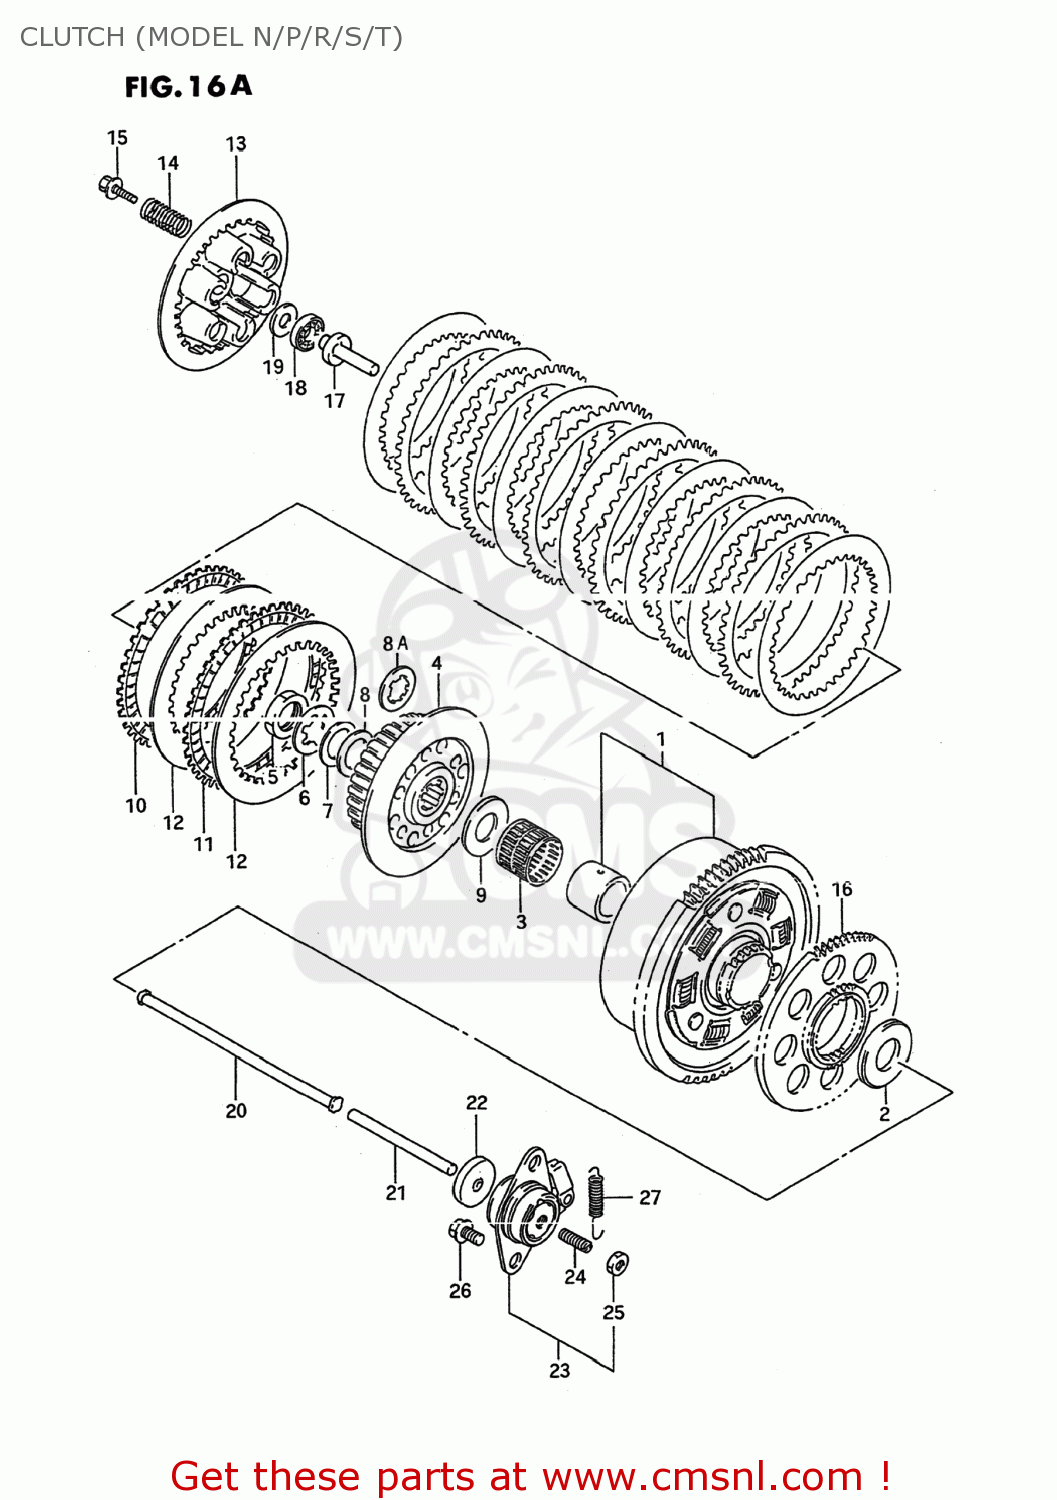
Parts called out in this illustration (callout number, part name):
1	GEAR ASSEMBLY,PRIMARY DRIVE
2	WASHER(25X54X2.5)
3	BEARING(35X40X35.8)
4	HUB,CLUTCH SLEEVE
5	NUT
6	WASHER,LOCK
7	WASHER
8	SHIM
8A	WASHER,LOCK
9	WASHER(25X50X2.5)
10	PLATE,CLUTCH DRIVE (NAS)
11	PLATE,CLUTCH DRIVE NO.2 (NAS)
12	PLATE,CLUTCH DRIVEN (NAS)
13	DISC,CLUTCH PRESSURE
14	SPRING
15	BOLT(6X25)
16	GEAR,GENERATOR DRIVE
17	PIECE,CLUTCH PUSH
18	BEARING(15X28X2)
19	WASHER
20	ROD,CLUTCH PUSH,R
21	ROD,CLUTCH PUSH,L
22	SEAL,OIL(6X34X5.5)
23	SCREW ASSY,CLUTCH RELEASE
24	SCREW(6X25)
25	NUT
26	BOLT
27	SPRING
